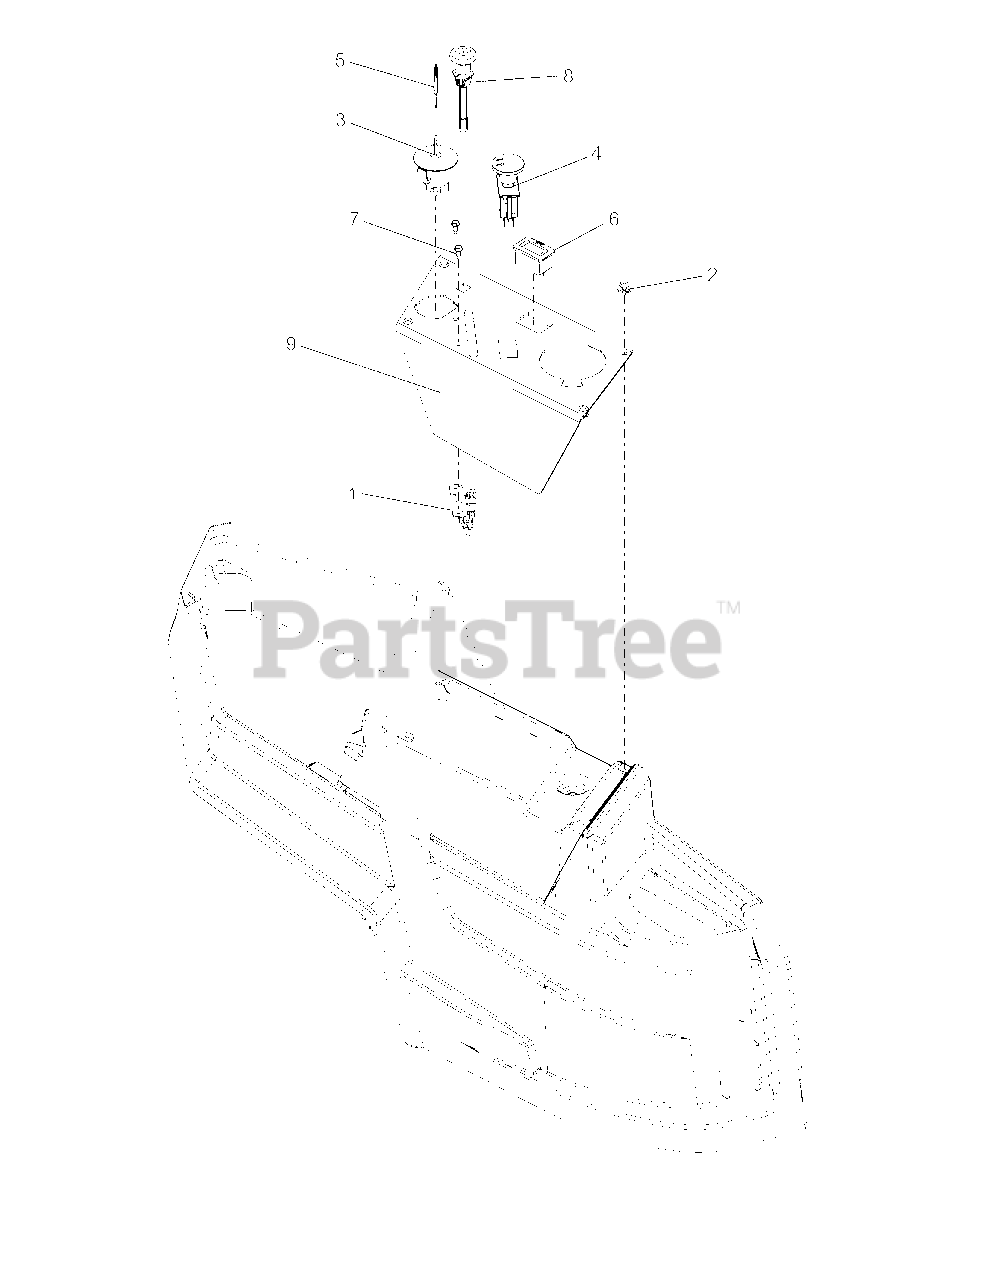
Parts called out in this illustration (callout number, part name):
1	CABLE - THROTTLE CONTROL
2	RIVET, PLASTIC .195 DIA.
3	KEYSWITCH-IGNITION 4 POS
4	SWITCH, CLUTCH (YELLOW)
5	KEY, IGNITION
6	HOUR METER
7	SCR,TAP #10-24X.50 HWH TR ZCC
8	CABLE - CHOKE, SNAP-IN
9	PANEL, CONTROL
